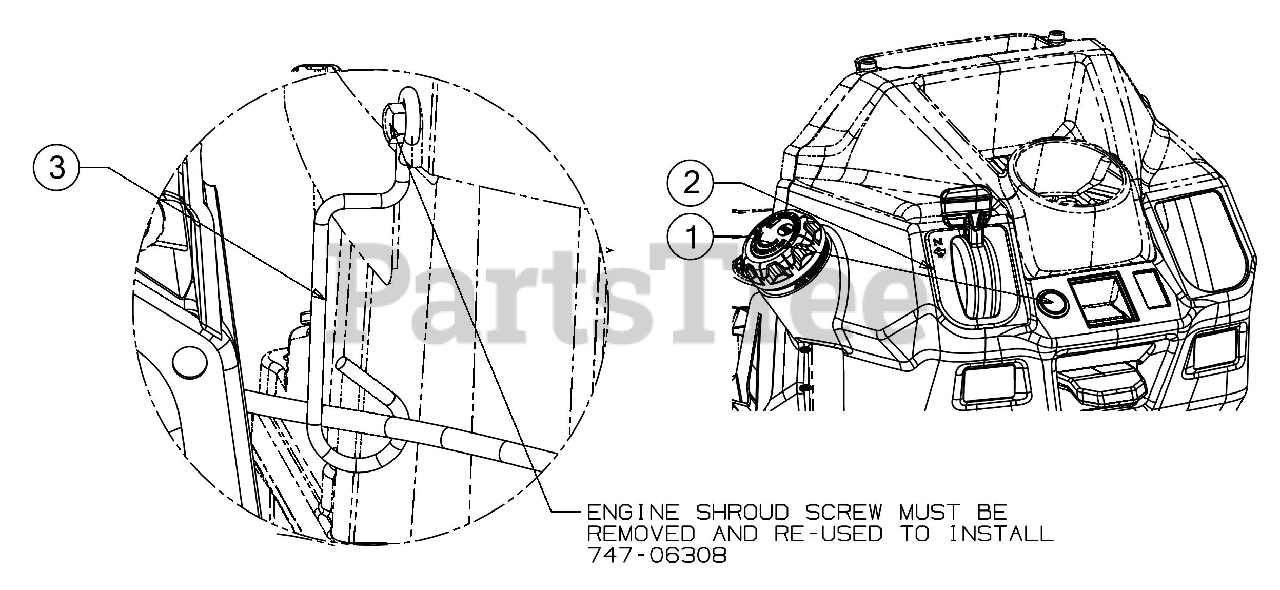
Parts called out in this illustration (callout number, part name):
1	CHOKE PLUG
2	THROTL/CHOKE CABLE 43.5X1.7
3	CABLE GUIDE WIRE
